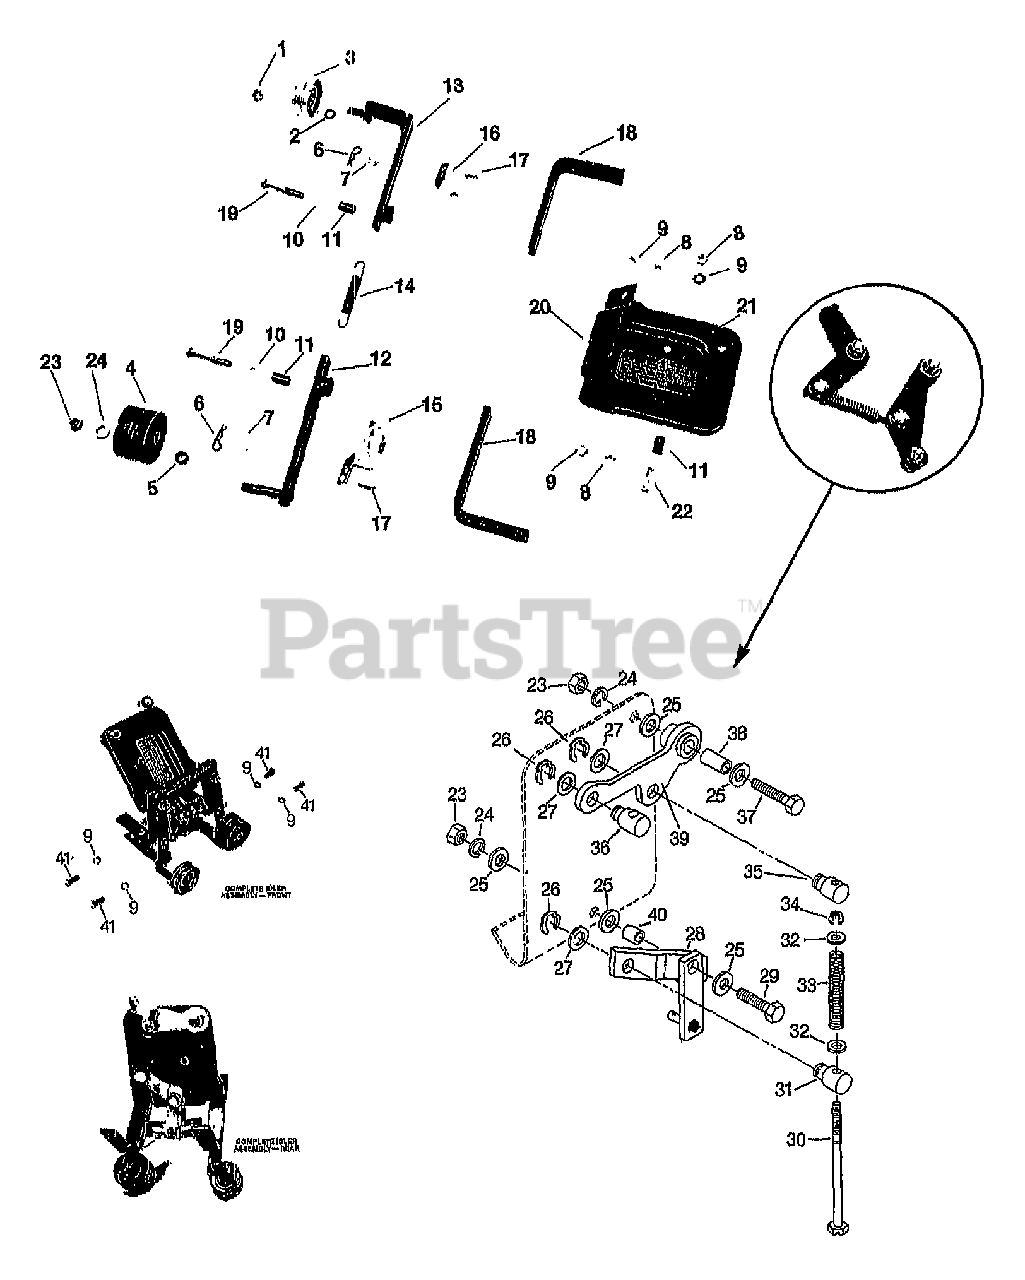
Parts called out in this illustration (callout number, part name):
1	NUT-LOCK 3/8-16 NYLON ZP
2	BUSHING-.54X.38X.08
3	IDLER-REV
4	PULLEY-IDLER FORWARD
5	SPACER-IDLER FWD
6	PIN-CLIP .08
7	WASHER-FLAT 1/4 SAE
8	NUT-HEX 5/16-18 ZP
9	WASHER-LK .312 ZP
10	WASHER-#.75X.32X.09 ZP
11	BUSHING-.438X.323X.712
12	ARM-IDLER FWD PNT
13	ASSM-IDLER REV @ DEPL
14	SPRING-.436 X 3.25
15	LINK-FWD
17	PIN-CLEVIS .375X.719 ZP
18	MOUNT BAR-PNT (20691)
19	BOLT-HH 5/16-18 X 2 G5 ZP
20	BASE-SHIFTING W/DECAL (INCL. #50112 DECAL)
21	DECAL-BELT WARNING INSTR. ON BELTS/PULLEYS
22	SCR-HH 5/16-18X1.25 G5ZP
23	NUT-HEX 3/8-16 ZP
24	WASHER-LK .375 @ DEPL
25	SPACER-.88X.385X.09 ZP
26	RING-KLIP .500 ZINC
27	WASHER-#.88X.51X.063 ZP
28	BELLCRANK-WELDMENT
29	SCR-HH 3/8-16X1.25
30	SCR-HH 1/4-20X4.5 G5
31	PIVOT-SLIDE
32	WASHER # ZP
33	SPRING-.52 X 3
34	RING-KLIP 5304-25
35	PIVOT-THREADED
36	PIVOT-ROD (FOR FORWARD/REVERSE LEVER)
37	BOLT-HH 3/8-16X1.5 FTH ZP
38	BUSHING-.5X.38X.665
39	RODCRANK
40	BUSHING-.5X.38X.4
41	SCR-HH 5/16-18X1.0 G5 ZP
